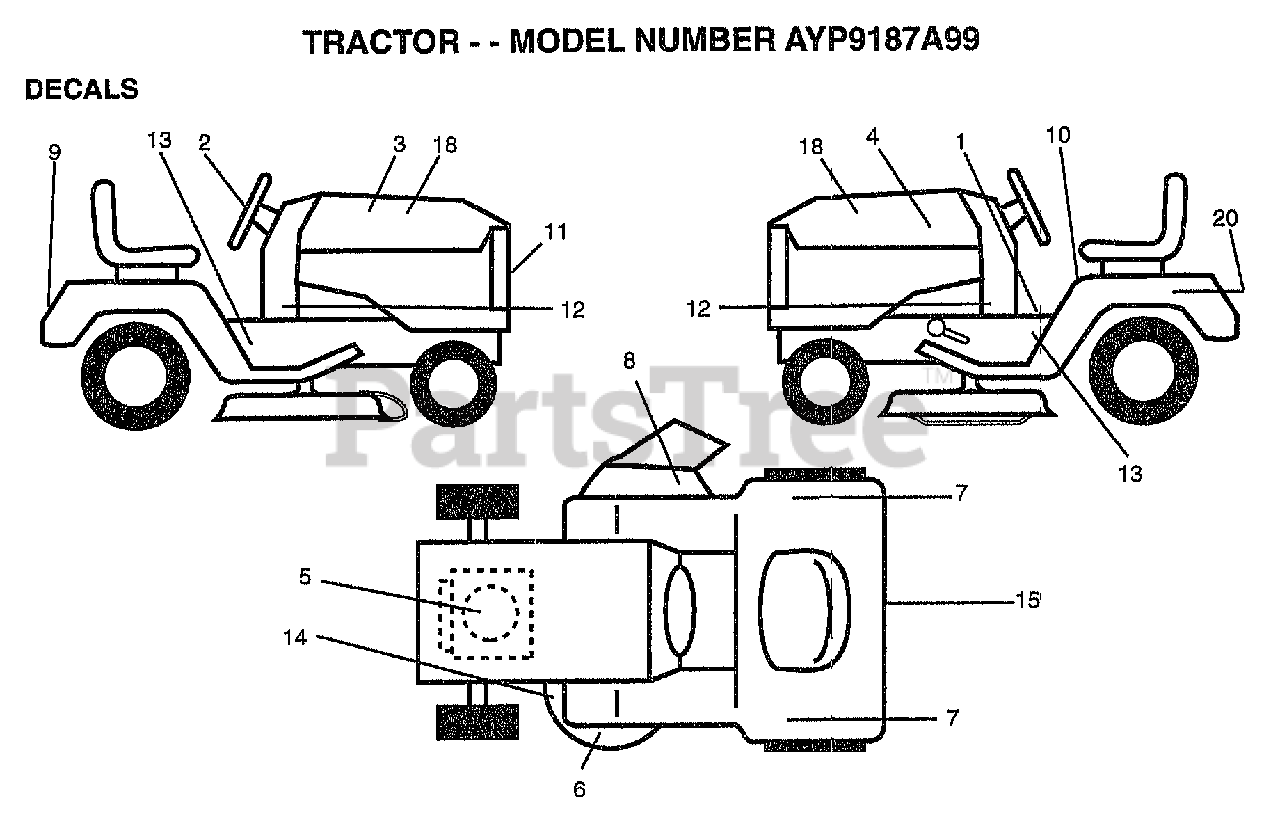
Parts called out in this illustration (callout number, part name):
1	"DEAL-OPER,INST."
2	DECAL STEER WHL
3	DECAL HOOD RH
4	DECAL HOOD LH
5	DECAL HP ENGINE
6	DECAL DECK MULCH
7	DECAL.FENDER.AUTO
8	DECAL DECK WIZ +
10	"DECAL DANGER,FEND"
11	DECAL.LENS.WIZARD
12	DECAL PANEL SIDE
13	"DECAL.CHASSIS.42"""
14	"DECAL-SCHEM,BELT"
15	DECAL DRAWBAR LH
18	NAMEPLATE.HD.WIZA
20	DECAL.BATRY.3-3908
